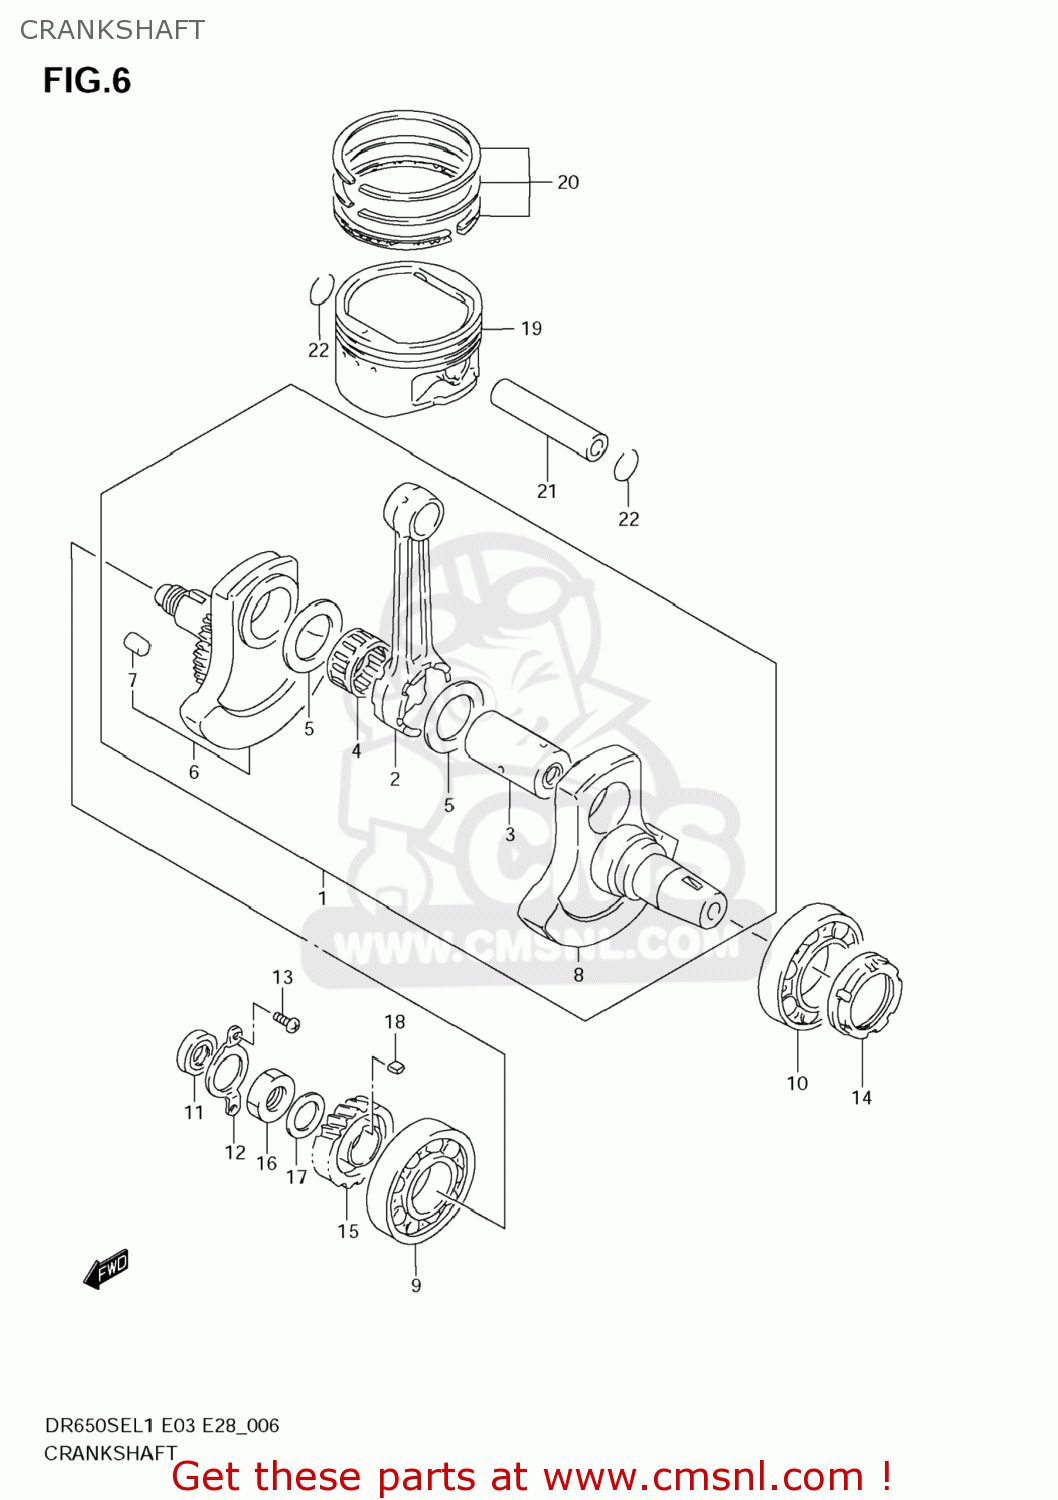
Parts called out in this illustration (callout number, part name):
1	CRANKSHAFT SET
2	CONNECTING ROD
3	PIN,CRANK
4	BEARING(37X47X25)
5	WASHER(37X55X1)
6	CRANKSHAFT SET,R
7	PIN(8X22.5)
8	CRANKSHAFT,L
9	BEARING(40X80X18)
10	BEARING(45X85X19)
11	SEAL,OIL(16X30X6)
12	RETAINER,CRANKSHAFT BEARING,R
13	SCREW
14	NUT,CRANKSHAFT BRG,L
15	GEAR,PRIMARY DRIVE(NT:28)
16	NUT
17	WASHER
18	KEY
19	PISTON (100.00MM)
20	RING SET,PISTON
21	PIN,PISTON
22	CIRCLIP
